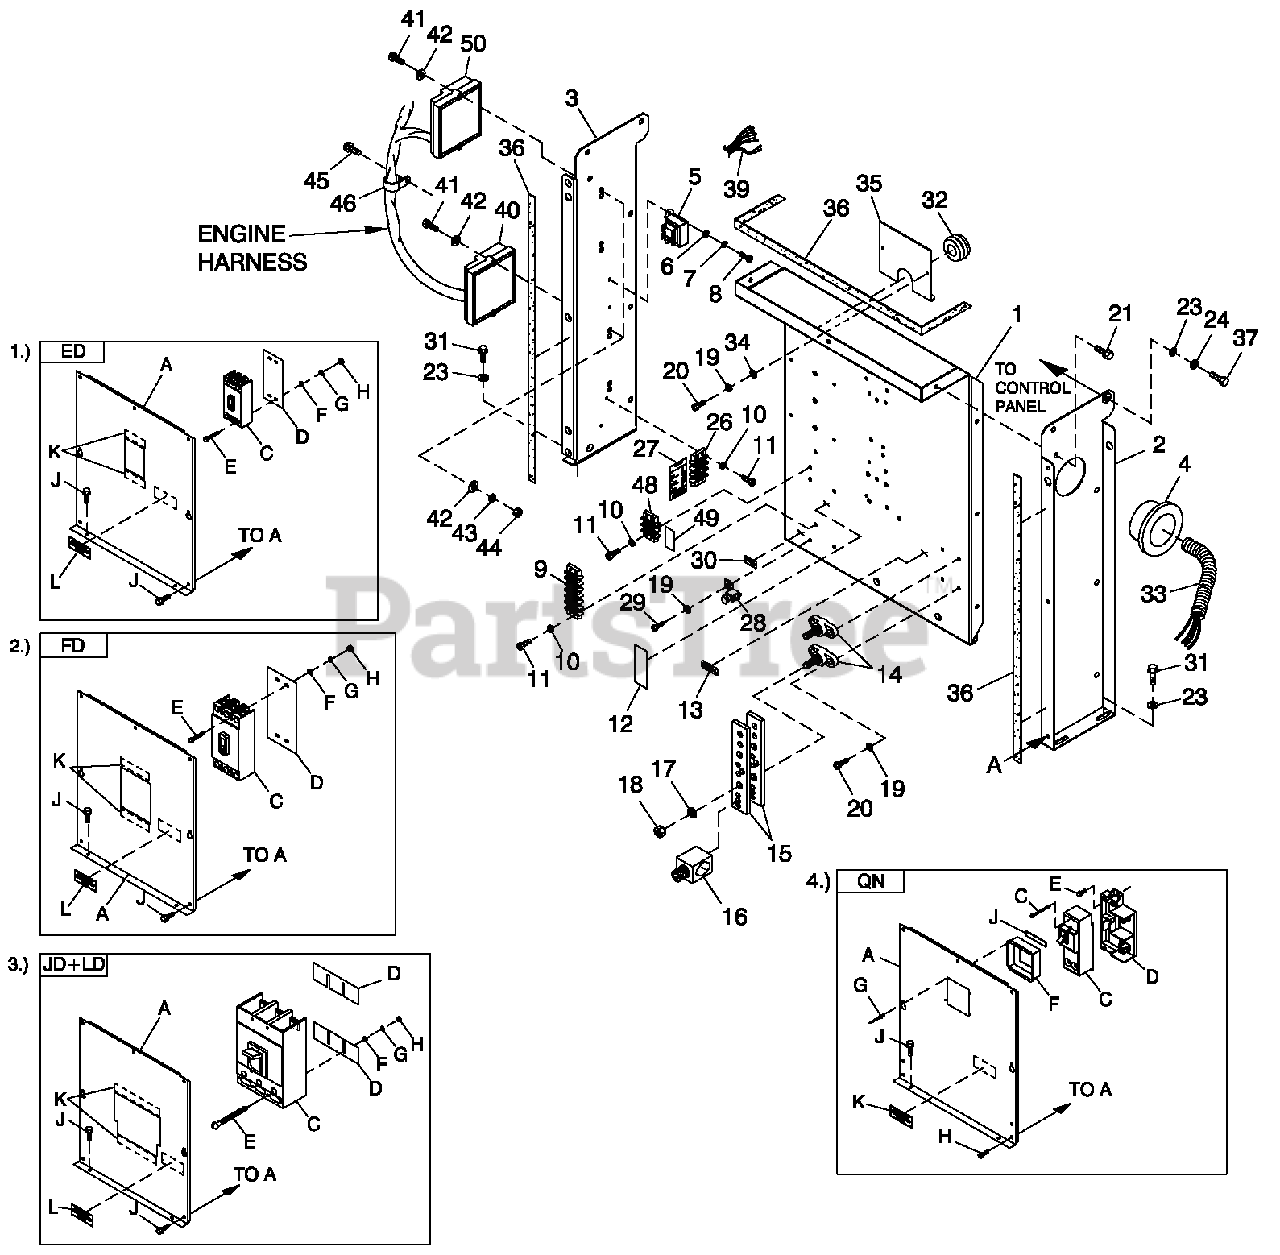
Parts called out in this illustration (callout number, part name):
1	PAN CB CONN BOX
1	UL CIRCUIT BREAKER (ED)
2	STAND RH CONTROL
2	UL CIRCUIT BREAKER (FD)
3	STAND LH CONTROL
3	UL CIRCUIT BREAKER (JD+LD)
4	BUSHING SNAP SB-2.5-31
4	UL CIRCUIT BREAKER (QN)
5	XFMR DUAL 120V/16V (FOR 120/240V & 277/480V UNITS)
6	WASHER FLAT M4
7	WASHER LOCK #8-M4
8	SCREW PHTT M4-0.7 X 10 ZYC
9	BLOCK TERM 20A 6 X 6 X 1100V
10	WASHER LOCK #6
11	SCREW PHTT #6-32 X 1/2 ZYC
12	DECAL RTS CUSTOMER CONNECTION
13	DECAL NEUTRAL
14	JUNCTION BLOCK 3/8-16
15	BUS BAR NEUTRAL BLOCK 390
16	LUG SLDLSS 600/250-1/0 X 1/4-28
17	WASHER LOCK 3/8
18	NUT HEX 3/8-16 STEEL
19	WASHER LOCK M5
20	SCREW PHTT M5-0.8 X 16 ZYC
21	SCREW THF M6-1 X 16 N WA Z/JS
23	WASHER FLAT 1/4-M6 ZINC
24	WASHER LOCK M6-1/4
26	BLOCK TERM 20A 6 X 3 X 1100V
27	DECAL CHARGER POWER 120VAC C2
28	LUG SLDLSS #6-14 X 13/64 CU
29	SCREW HHTT #10-32 X 3/8 CZ
30	DECAL GROUND LUG
31	SCREW HHTT M6-1.0 X 16 ZYC
32	GROMMET 1.25 X .25 X .75
33	CONDUIT FLEX 2.0" ID (36" LG)
34	WASHER FLAT M5
35	PLATE WIRE SNGL GALV
36	TAPE ELEC 1/2 FOAM (AS REQ'D)
37	SCREW HHC M6-1.0 X 16 G8.8
39	HARNESS, TRANSFORMER ADAPTER
40	PCB ENCLOSURE ASSY 4.2L IGN MD
41	SCREW PPHM #10/32 X 2
42	WASHER FLAT #10 ZINC
43	WASHER LOCK #10
44	NUT HEX #10-32 STEEL
45	SCREW THF M6-1 X 16 N WA Z/JS
46	CLAMP VINYL 1.06 X .406 Z
47	SEAL WEATHER .45"DIA
48	BLOCK TERM 20A 2 X 6 X 1100V
49	DECAL GTS CUSTOMER CONNECTION
50	ASSY PCB IGN MOD 2.4L NO-TURBO
A	COVER ED CB SHORT STND
C	CB 0050A 3P 480V S ED4 LL
D	INSULATOR CB S (ED-3P)
E	SCREW RHM #10-32 X 4-1/2
F	WASHER FLAT #10 ZINC
G	WASHER LOCK #10
H	NUT HEX #10-32 STEEL
J	SCREW THF M6-1 X 16 N WA Z/JS
K	TAPE ELEC 1/2 FOAM (AS REQ'D)
L	DECAL CUSTOMER CONNECT INSIDE
A	COVER CB CONN BOX
C	CB 0150A 3P 600V S FD6 LL
D	INSULATOR CB FD FRAME 30MIL
E	SCREW SHC 1/4-20 X 4.5 G8.8 NZ
F	WASHER FLAT 1/4-M6 ZINC
G	WASHER LOCK M6-1/4
H	NUT HEX 1/4-20 STEEL
A	COVER JD/LD CB SHRT STAND
C	CB 0300A 3P 600V S JD6 LL
D	INSULATOR CIRCUIT BR. JD/LD
E	SCREW RHM 1/4-20 X 3
A	COVER QN FRM CB
C	CB 0150A 2P 240V S QN2 LL
D	BASE, QN CIRCUIT BREAKER
E	SCREW HHTT M5-0.8 X 10 BP
F	COVER QN CB DISH
G	RIVET POP .125 X .275 SS
H	SCREW THF M6-1X16 N WA Z/JS
J	TAPE ELEC 1/2 FOAM (AS REQ'D)
K	DECAL CUSTOMER CONNECT INSIDE
